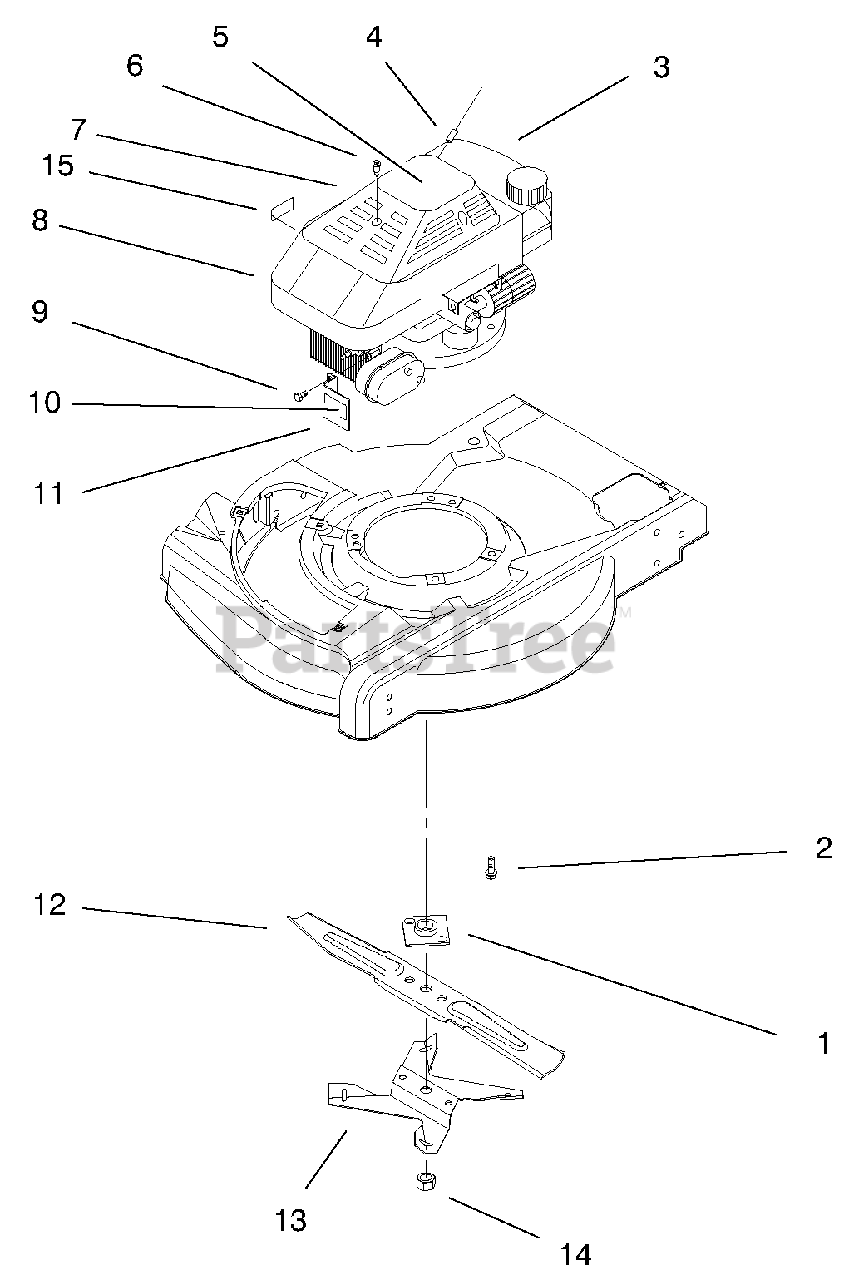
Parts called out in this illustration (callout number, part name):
1	Plate & Collar Assembly
2	Screw-Engine
3	Engine
4	Stop-Rope
5	Decal-Shroud Top
6	Screw-Recoil Cover
7	Cover-Starter
8	Shroud-Engine
9	Screw-Hex Socket Hd.
10	Decal-Warning
11	Guard-Muffler
12	Blade-21"
13	Fan-Mulching
14	Nut-Blade
15	Decal-Oil Instruction
